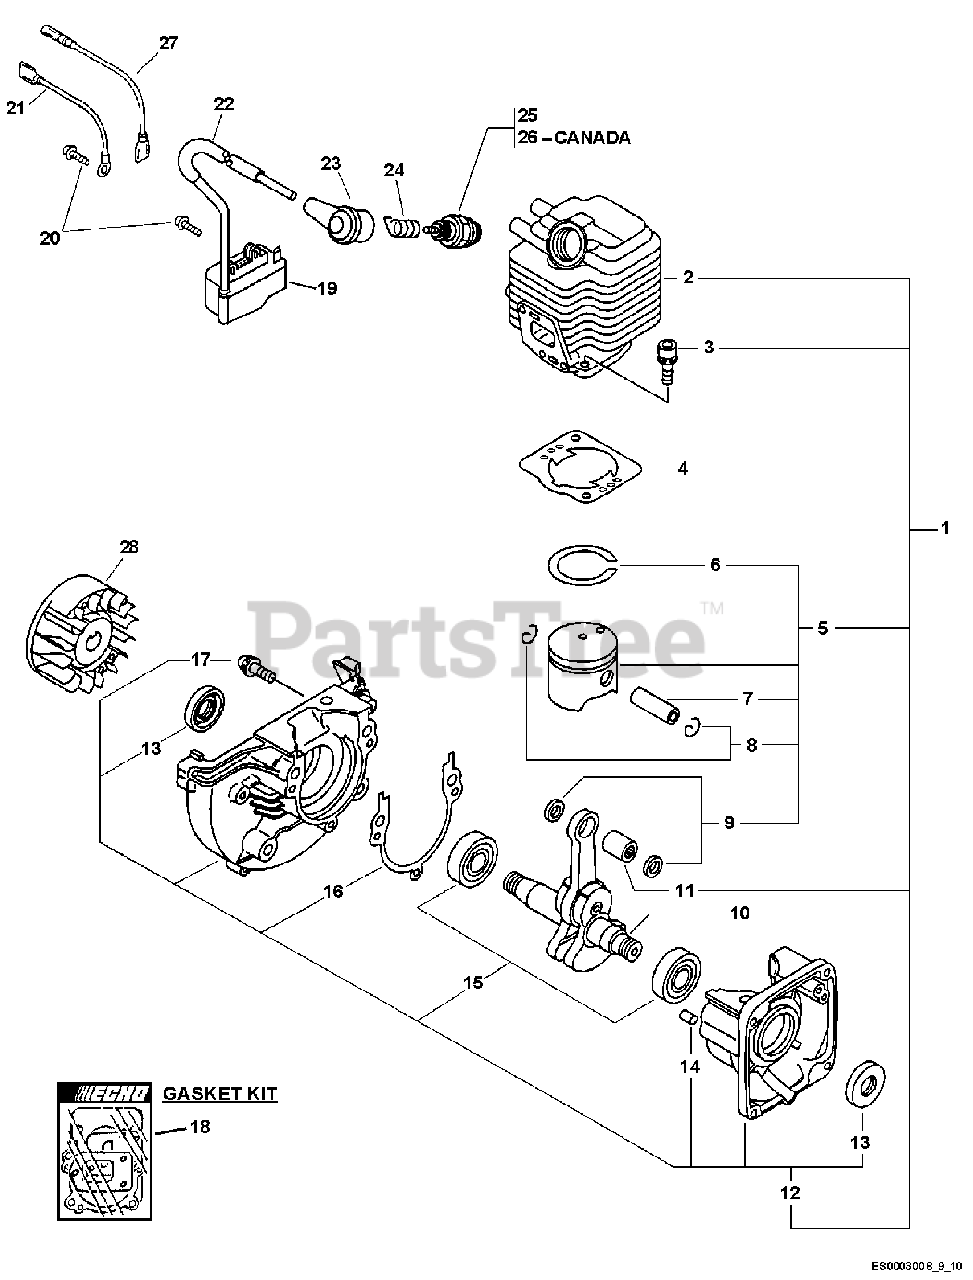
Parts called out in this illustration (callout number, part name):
1	SHORT BLOCK
2	CYLINDER
3	BOLT 5×22
4	GASKET, CYLINDER
5	PISTON KIT
6	RING, PISTON
7	PIN, PISTON 8
8	RING, SNAP
9	WASHER, THRUST
10	CRANKSHAFT ASSY
11	BEARING, NEEDLE 8
12	CRANKCASE KIT
13	SEAL, OIL 12
14	PIN, LOCATING 4
15	BEARING, BALL - 6201 C3
16	GASKET, CRANKCASE
17	BOLT 5×28
18	GASKET KIT
19	COIL, IGNITION
20	BOLT 4×20
21	LEAD
22	TUBE, INSULATOR
23	CAP, SPARK PLUG
24	TERMINAL, SPARK PLUG
25	SPARK PLUG - BPM8Y
26	SPARK PLUG - BPMR8Y
27	LEAD - IGNITION
28	FLYWHEEL
